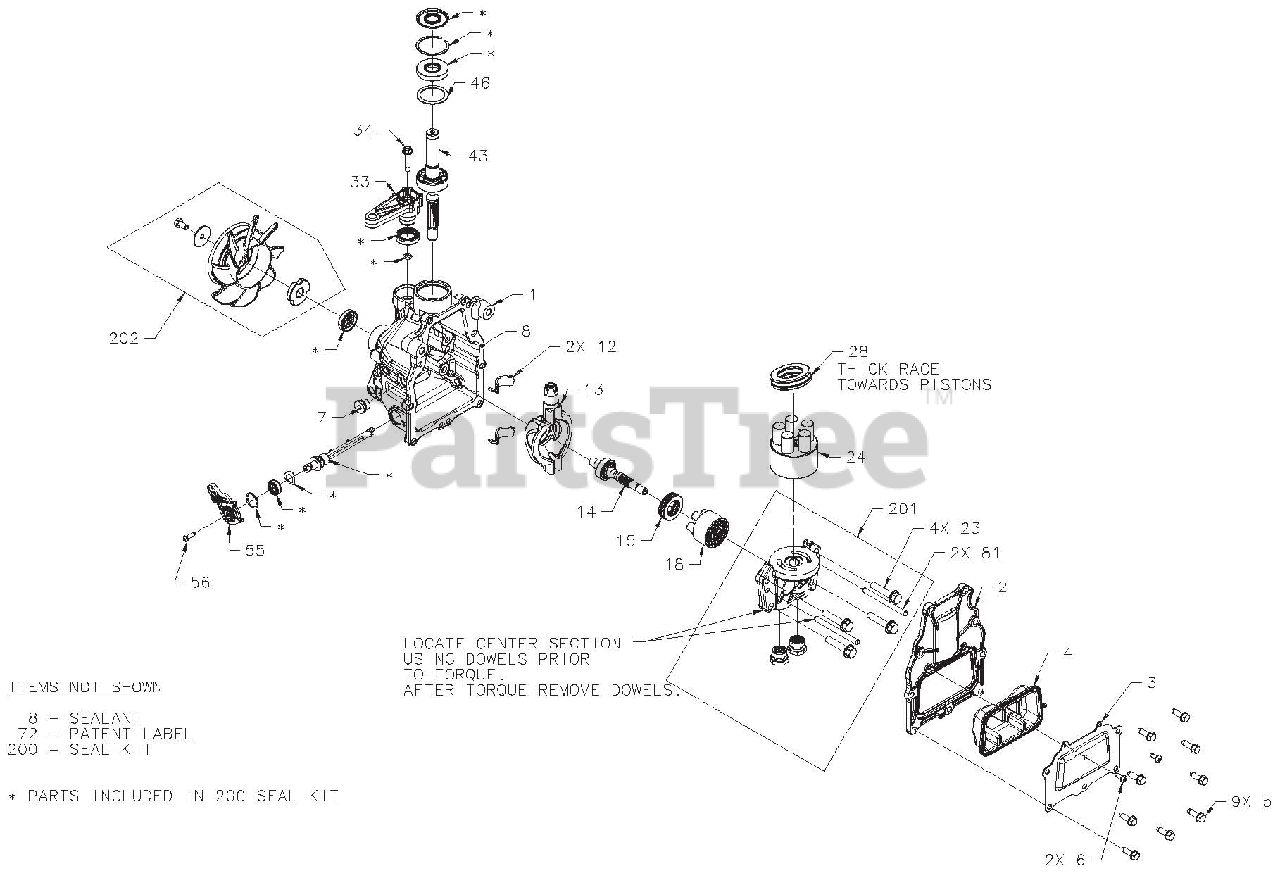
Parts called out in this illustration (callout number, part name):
1	Housing Main, Shot
2	Cover
3	Plate, Expansion
4	Bladder
5	Screw, Hex Flange 1/4-20 x .75
6	Bolt, Self Tapping 10-32 x .5
7	Plug, 9/16-18 Straight Thread Socket Head
8	Tube, Sealant
12	Bearing, Cradle
13	Swash Plate
14	Kit, Input Shaft
15	Bearing, 21 x 35 x 10
18	Kit, 3cc Block
23	Screw, HFHCS 5/16-18 x 1.5
24	Kit, 10cc Block
28	Bearing, Thrust 30 x 52 x 13
33	Arm, Control
34	Screw, Hex Washer 1/4-20 x 1.125
43	Kit, Motor Shaft
46	Washer, Flat 1.23 x 1.57 x .04
55	Arm, Bypass
56	Screw, M4 x 16, Wuplast
62	Hub, Pulley Dia 1.41
72	Label, Patent
81	Pin, Straight Headless
200	Kit, Seal
201	Kit, Center Section
202	Kit, Fan/Pulley
